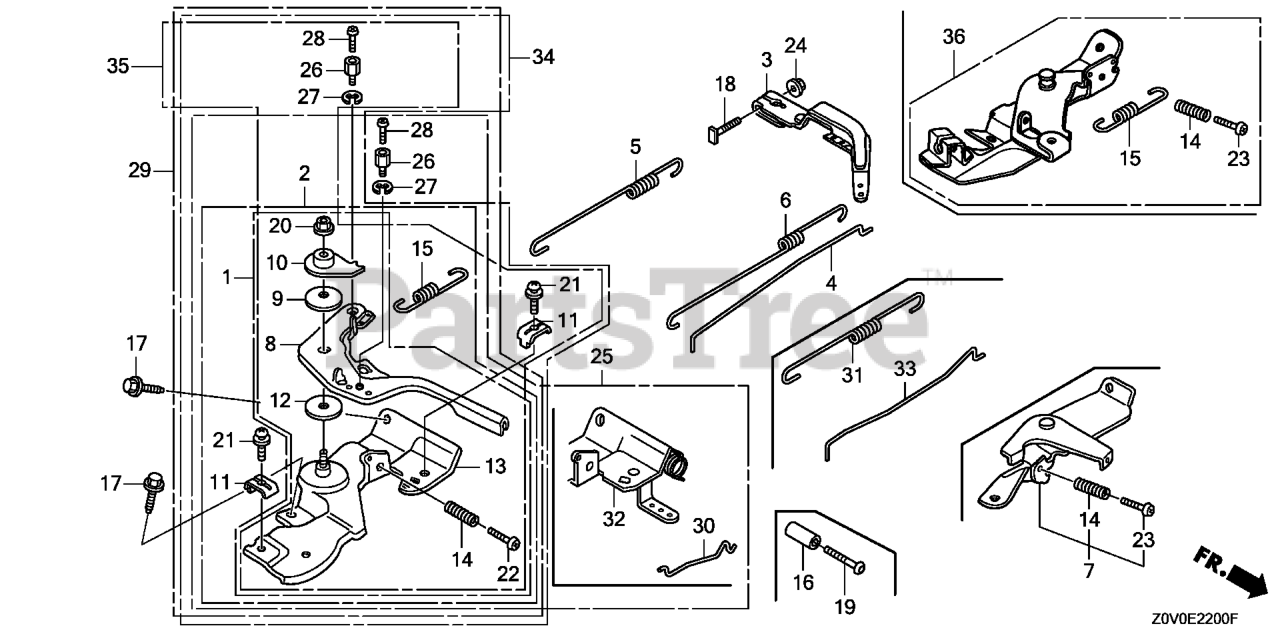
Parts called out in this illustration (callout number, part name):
2	CONTROL ASSY. (REMOTE)
3	ARM, GOVERNOR
4	ROD, GOVERNOR
5	SPRING, GOVERNOR
6	SPRING, THROTTLE RETURN
8	LEVER, CONTROL
9	SPRING, LEVER
10	WASHER, CONTROL LEVER
11	HOLDER, CABLE
12	SPACER, CONTROL LEVER
13	BASE, CONTROL
14	SPRING, CONTROL ADJUSTING Use from Engine SN 2327377.
15	SPRING, CABLE RETURN
17	BOLT, FLANGE (6X12) (CT200)
18	BOLT, GOVERNOR ARM
20	NUT, SELF-LOCK (6MM)
21	SCREW, PAN (5X16)
22	SCREW, PAN (5X25)
24	NUT, FLANGE (6MM)
